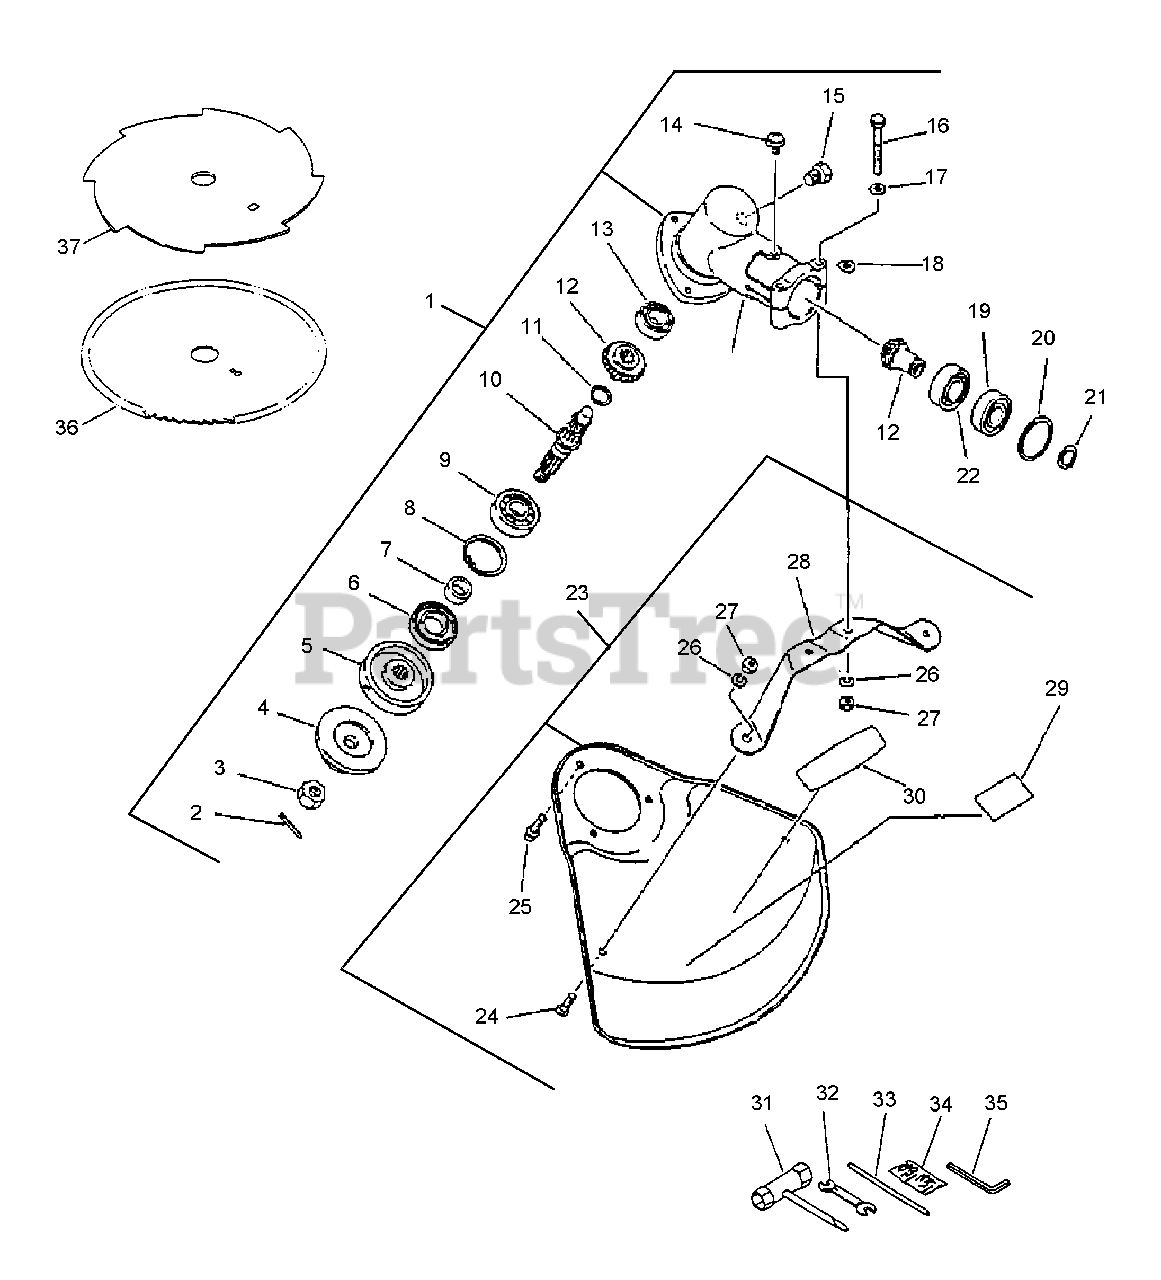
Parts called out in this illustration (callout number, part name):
1	GEAR CASE ASSY
2	PIN, SPLIT - 2X22
3	NUT - 10 -- LEFT HAND
4	ADAPTOR, BLADE - LOWER
5	ADAPTOR, BLADE - UPPER
6	SEAL, OIL
8	RING, RETAINING - 32
9	BEARING, BALL - 6201
10	GEAR - SHAFT
11	RING, RETAINING - 12
12	GEAR SET - BEVEL
13	BEARING, BALL - 6000
14	SCREW - 5X10
15	BOLT - 8X8
16	BOLT - 5X40
17	WASHER - 5
19	BEARING, BALL - 6001
20	RING, RETAINING - 28
21	RING, RETAINING - 12
22	BEARING, BALL - 6001C3
23	DEBRIS SHIELD KIT
24	SCREW - 5X8
25	SCREW - 5X10
26	LOCKWASHER - 5
28	BRACKET, SHIELD
29	LABEL - DANGER
30	LABEL - ECHO
31	T-WRENCH - 17X19mm
32	SPANNER - 8X10mm
33	LOCKING TOOL
34	PIN, SPLIT - 2X22
35	HEX KEY - 4mm
36	BLADE, 25mm ID - 80 TOOTH -- 10" (25cm)
37	BLADE - 8 TOOTH
